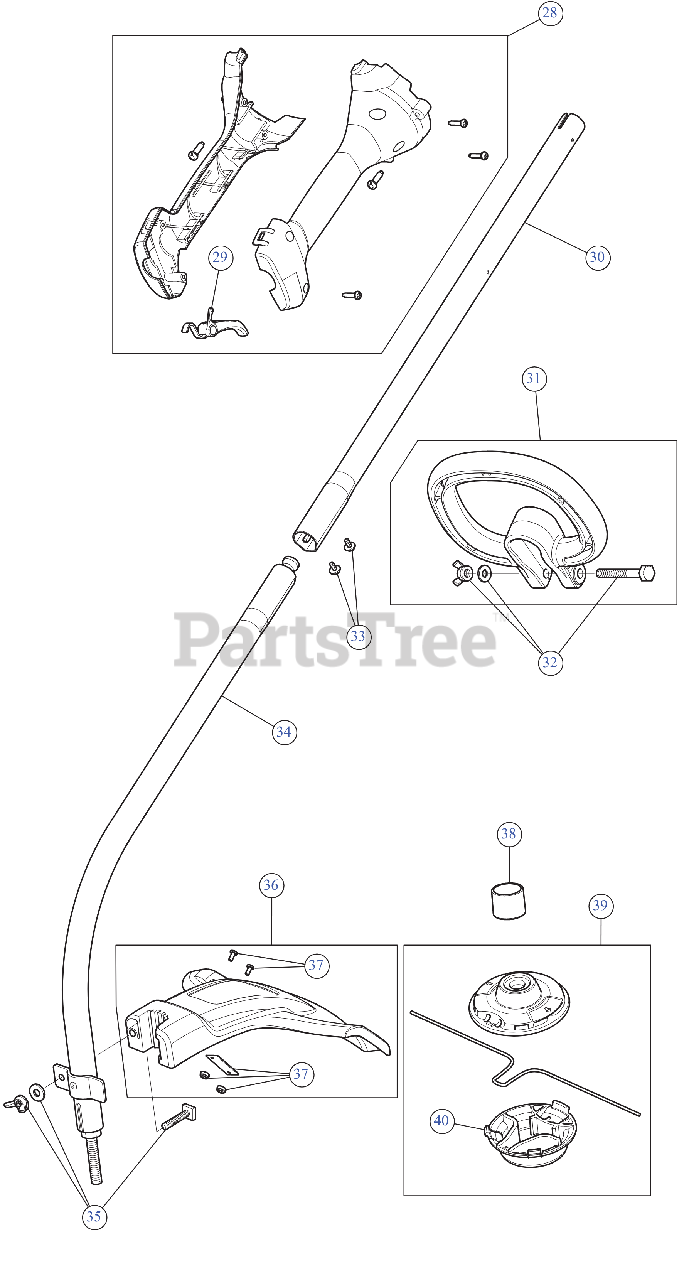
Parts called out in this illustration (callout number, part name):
28	THROTTLE GRIP ASSEMBLY
29	THROTTLE TRIGGER
30	UPPER BOOM ASSEMBLY
31	HANDLE
32	HANDLE HWD
33	SCREW 8-32X3/8
35	BLADE GUARD MOUNTING HARDWARE
36	GUARD ASSEMBLY
37	BLADE ASSEMBLY CUTOFF
38	WEED GUARD
39	FIXED HEAD
40	HEAD FIXED LINE BT
